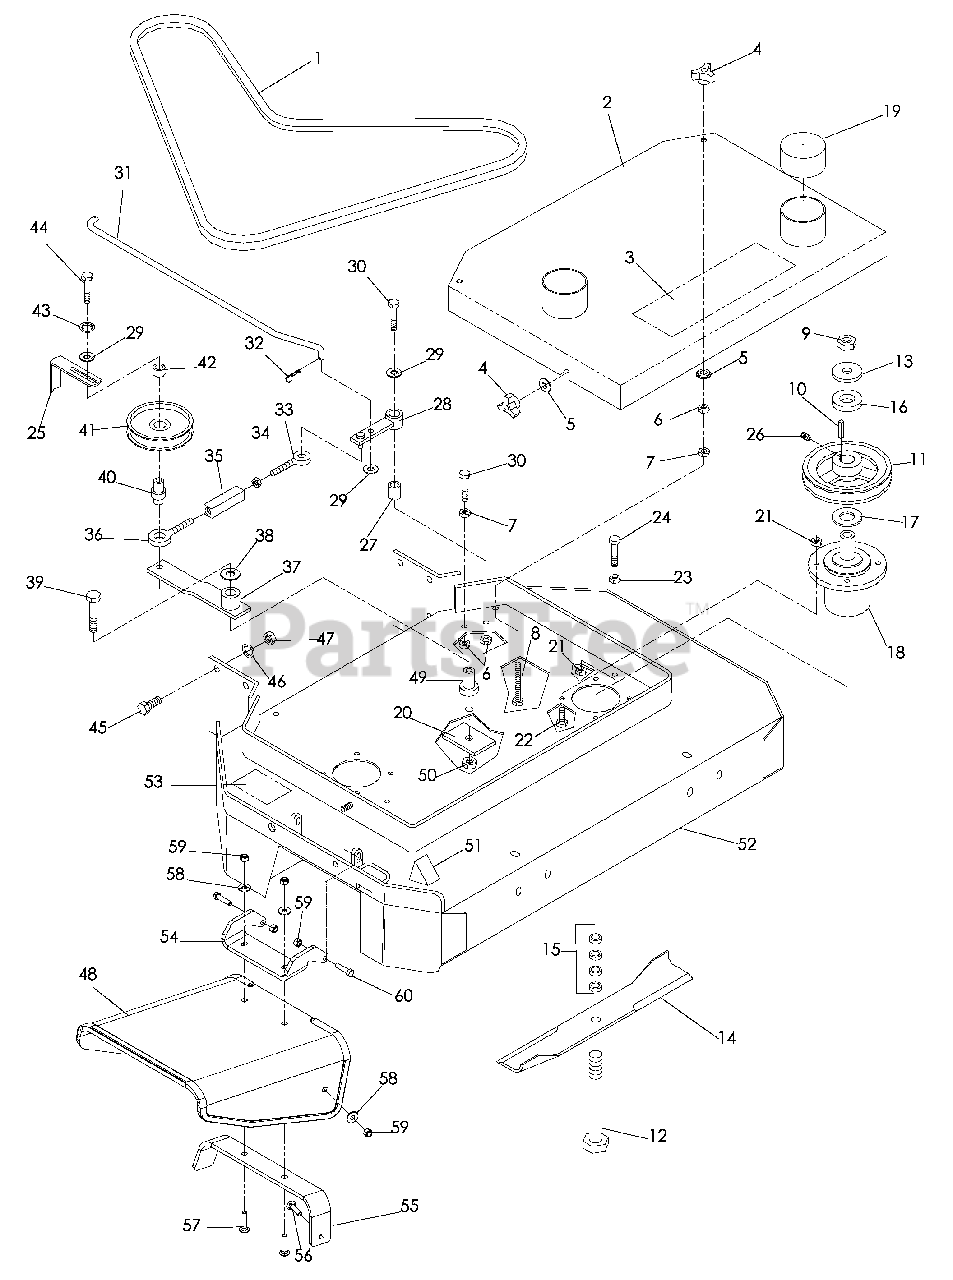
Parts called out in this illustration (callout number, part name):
1	36" DECK BELT
2	36" BELT SHIELD
3	DECAL, HUSQVARNA
4	KNOB, THREE PRONG
5	WASHER 3/8, SEALING
6	NUT 3/8-16 CENTERLOCK
7	NUT 3/8 -16 WHIZLK
8	TAPBOLT 3/8 -16 x 4½
9	NUT 5/8-18
10	KEY ¼ SQ x 11/8
11	PULLEY W/SETSCREWS
12	HCS 5/8-18 x 8½
13	SUPPORT WASHER
14	BLADE 18"(36)
15	BLADE SPACERS
17	BUSHING 10 GA
18	HOUSING ASSM
19	TUBE CAP PAD (NOT USED 32")
20	NUT 5/16-18
21	HCS 5/16-18 x 1
22	NUT 5/16-18 WHIZLK
23	HCS 5/16-18 x 3
25	SETSCREW 5/16 NYLOC
26	SLEEVE BUSHING
27	ENGAGEMENT ARM
28	WASHER 3/8
29	WASHER 3/8
30	HCS 3/8 -16 x 2¼
31	BLADE ROD 32 & 36
32	COTTER HAIRPIN, #2
33	EYEBOLT, RH
34	NUT 5/16-18
35	TURNBUCKLE
36	EYEBOLT, LH
39	HCS ½-13 x 2¾
40	EYEBOLT PIVOT
41	IDLER PULLEY
43	LOCKWASHER 3/8
44	HCS 3/8 -16 x 2½
45	HCS 7/16-14 x 1½
46	LOCKWASHER 7/16
47	NUT 7/16-14
48	CHUTE, RUBBER
49	IDLER SPINDLE
50	NUT ½-13 NYLOC
51	DECAL, CPSC
52	DECK, 36" W/DECALS
53	DECAL, DANGER
54	PIVOT BRACKET
55	REINFORCE BRACKET
56	RHSNB 5/16-18 x 1¼
57	RHSNB 5/16-18 x 1½
58	WASHER 5/16
59	NUT 5/16-18 NYLOC
60	HCS 5/16-18 x 1¼
